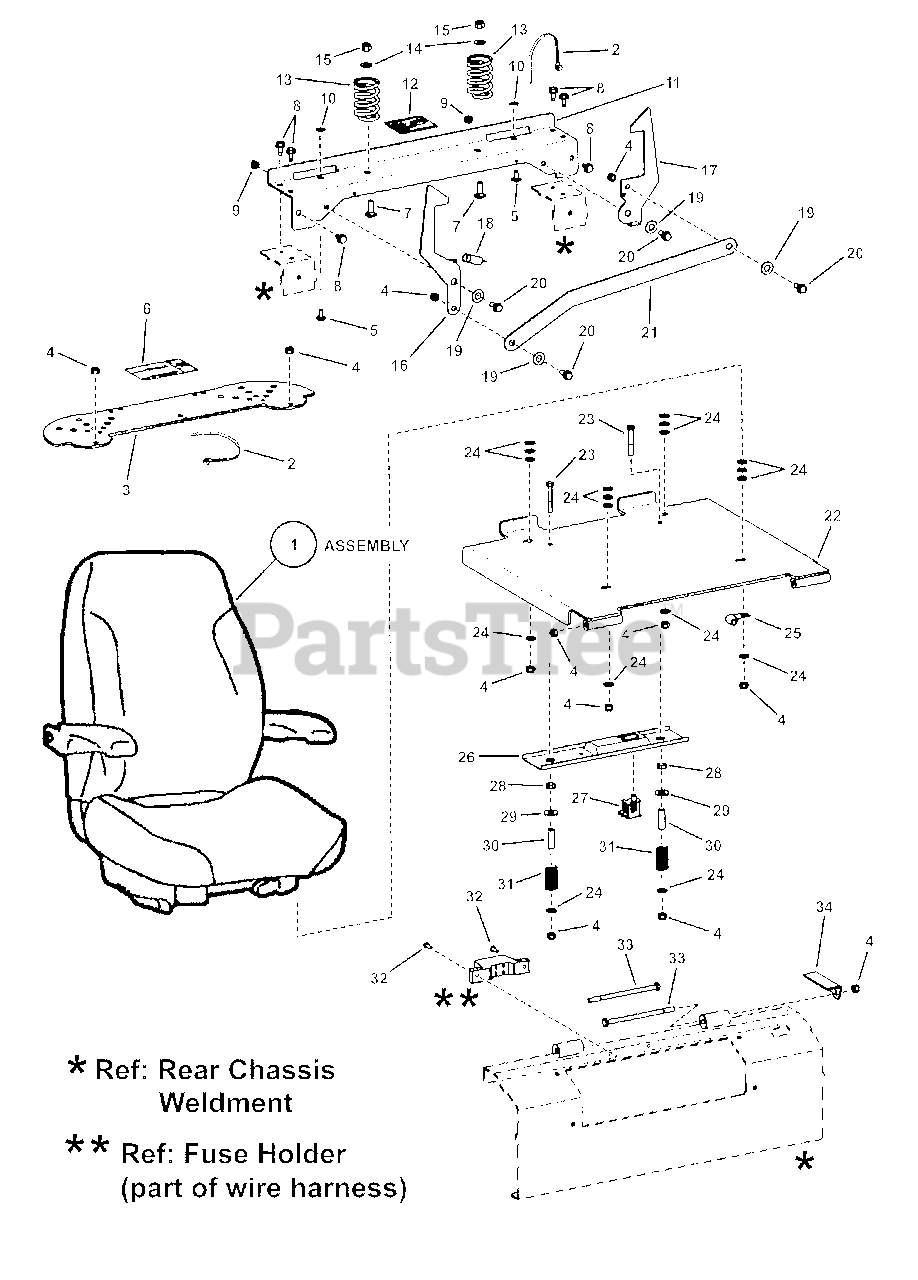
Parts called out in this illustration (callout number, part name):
1	SEAT ASSY, Mid Back Trim Line Static Suspension
2	CABLE TIE, 7" Long
3	FAN GUARD
4	NUT, 5/16-18 HEX NYLON LOCK
5	BOLT, 5/16-18 x 5/8" Short Neck Carriage, GR 5
6	DECAL, Caution Fan
7	BOLT, 3/8-16 x 1" Square Neck Carriage GR 5
8	SCREW, 5/16-18 x 5/8" Hex Washer Self-Tap
9	NUT, 5/16-18 Hex Center Lock
10	BOLT RETAINER, 5/16" Bolt
11	CROSSMEMBER, Seat Support
12	DECAL, Oil Level Reservoir
13	SPRING, Compression- Seat Support
14	WASHER, 3/8" SAE Flat
15	NUT, 3/8-16 HEX NYLON LOCK
16	SEAT LATCH, Left
17	BRACKET, Seat Latch, NZMX
18	SPRING, Extension
19	WASHER .47 x .92 x .065 Flat
20	SHOULDER BOLT, 5/16-18
21	LINK, Seat Latch
22	WELDMENT, Seat Pan
23	BOLT, 5/16-18 X 2", GD5
24	WASHER, 5/16" Flat
25	CLIP, Open J 3/8" Cushioned
26	HOLDER, Seat Switch
27	SWITCH, Seat, NC
28	BUSHING, Seat (Black Nylon)
29	SPACER/WASHER
30	SPACER
31	SPRING, Compression
32	SCREW, #10-32 x 5/8" Hex Washer Self-Tap, GR 5
33	SCREW, 5/16-18 x 5-1/2" Hex Head Cap, GR 5
34	BRACKET, Seat Stop, NZMX
